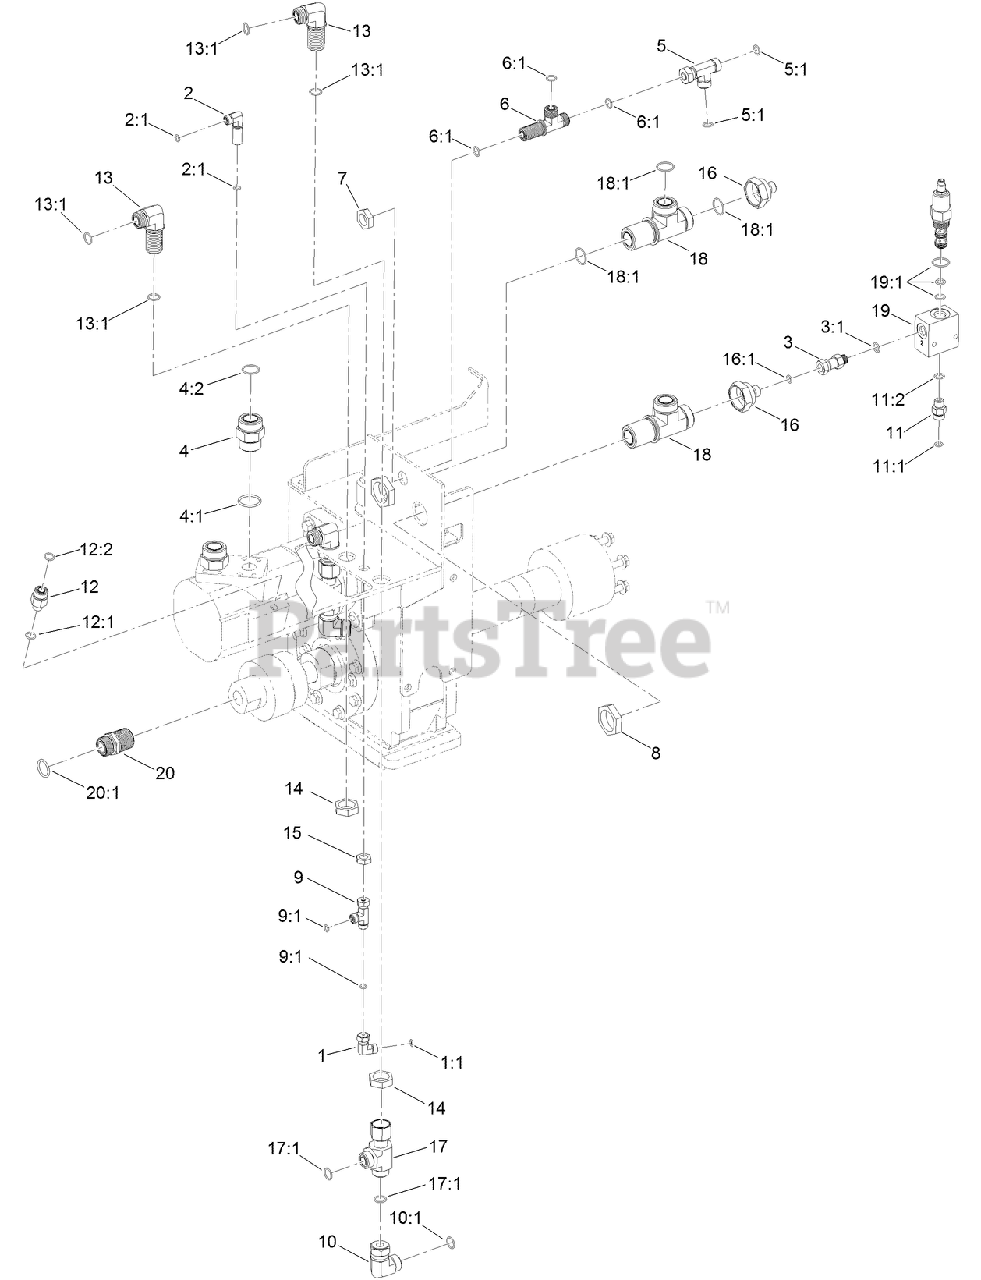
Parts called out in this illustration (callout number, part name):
1	FITTING-ADAPTOR
1:1	O-RING
2	ELBOW-UNION BULKHEAD
2:1	O-RING
3	CONNECTOR-SWIVEL, STRAIGHT
3:1	O-RING
4	FITTING-STRAIGHT
4:1	O-RING
4:2	O-RING
5	FITTING-HYD, TEE
5:1	O-RING
6	FITTING-TEE
6:1	O-RING
7	NUT-BULKHEAD
8	NUT-BULKHEAD
9	FITTING-HYD
9:1	O-Ring
10	FITTING-HYD-90
10:1	O-RING
11	FITTING-STRAIGHT
11:1	O-RING
11:2	O-RING
12	FITTING-STR
12:1	O-RING
12:2	O-RING
13	FITTING-BULKHEAD, 90 DEG
13:1	O-RING
14	NUT-LOCK, BULKHEAD
15	NUT-LOCK
16	FITTING-REDUCER
16:1	O-RING
17	FITTING-TEE
17:1	O-RING
18	FITTING-TEE, BULKHEAD
18:1	O-RING
19	PRESSURE RELIEF VALVE ASM
19:1	SEAL KIT
20	FITTING-STRAIGHT
20:1	O-RING
